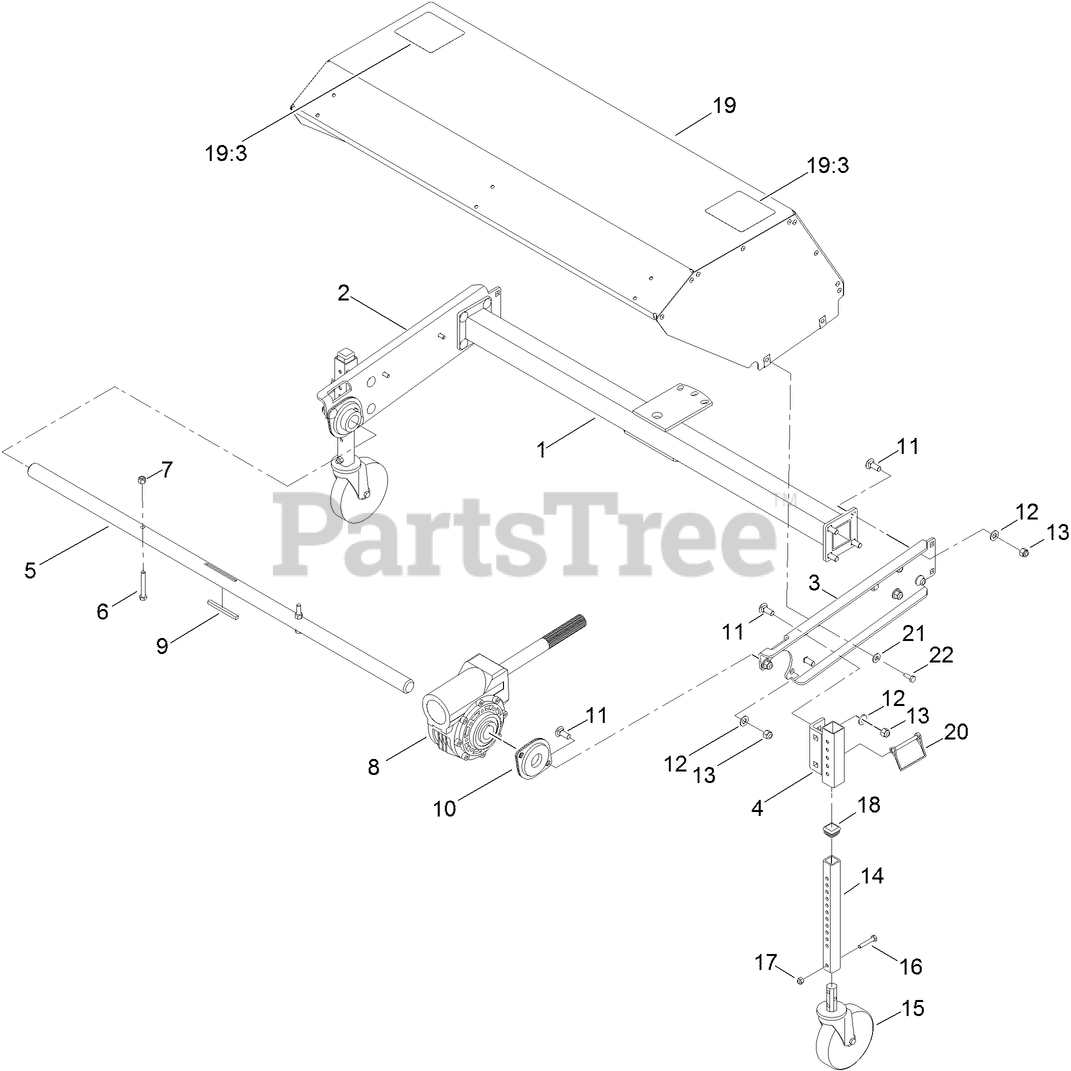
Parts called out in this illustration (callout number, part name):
2	ARM-RIGHT
3	ARM-LEFT
4	CASTER-BRACKET
6	SCREW-HH
7	NUT-LOCK, NI
8	GEARBOX-WORM
9	KEY-STRAIGHT
10	BEARING-FLANGE
11	BOLT-CARR
12	WASHER-FLAT
13	NUT-LOCK, NI
14	TUBE-SQUARE, HEIGHT ADJUST
15	CASTER-WHEEL
16	SCREW-HH
17	NUT-LOCK, NI
19	BROOM HOOD ASM
19:3	DECAL-WARNING
20	PIN-WIRE, LOCK
21	WASHER-FLAT
22	SCREW-HH
